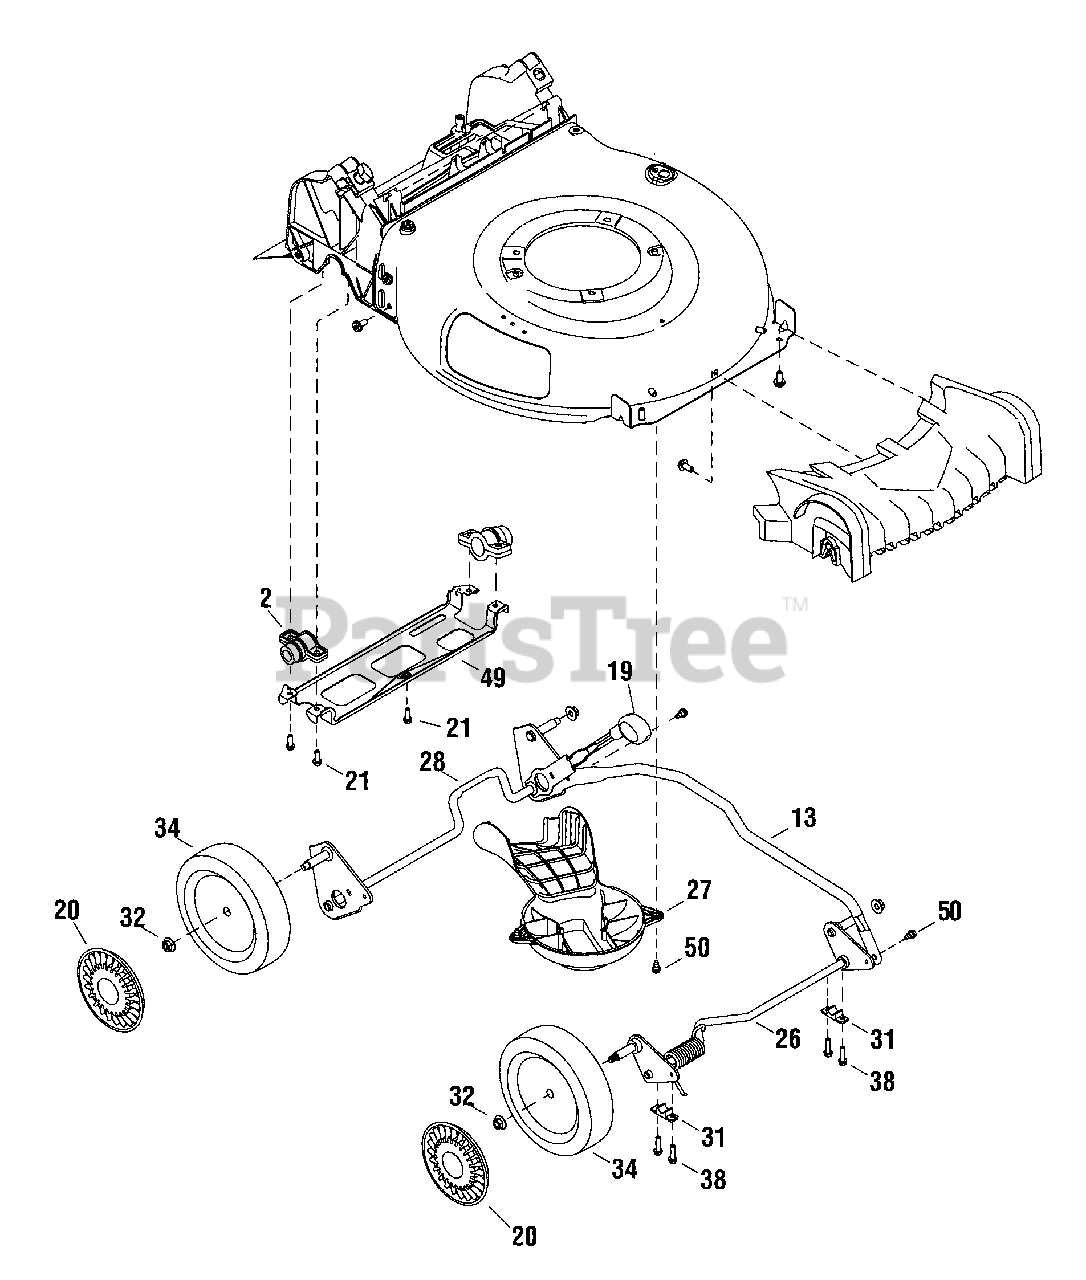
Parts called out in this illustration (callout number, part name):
2	ASSEMBLY, Bearing
13	BRACKET, Cross
19	KNOB, Adjustment Lever
20	HUBCAP, Front, 8" Silver
21	SCREW, 1/4-15 x 1-1/4
26	AXLE ASSEMBLY, Front
27	BAFFLE, Engine
28	AXLE ASSEMBLY, Rear
31	BUSHING, Lock
32	NUT, Hex Flange, Nylock, 3/8-16
34	WHEEL, 8 x 2, Black
38	SCREW, 1/4-15X3/4, Self-Tapping, BZ
49	SUPPORT, Rear Bracket
50	BOLT, Shoulder, 1/4-20 x 1/2
